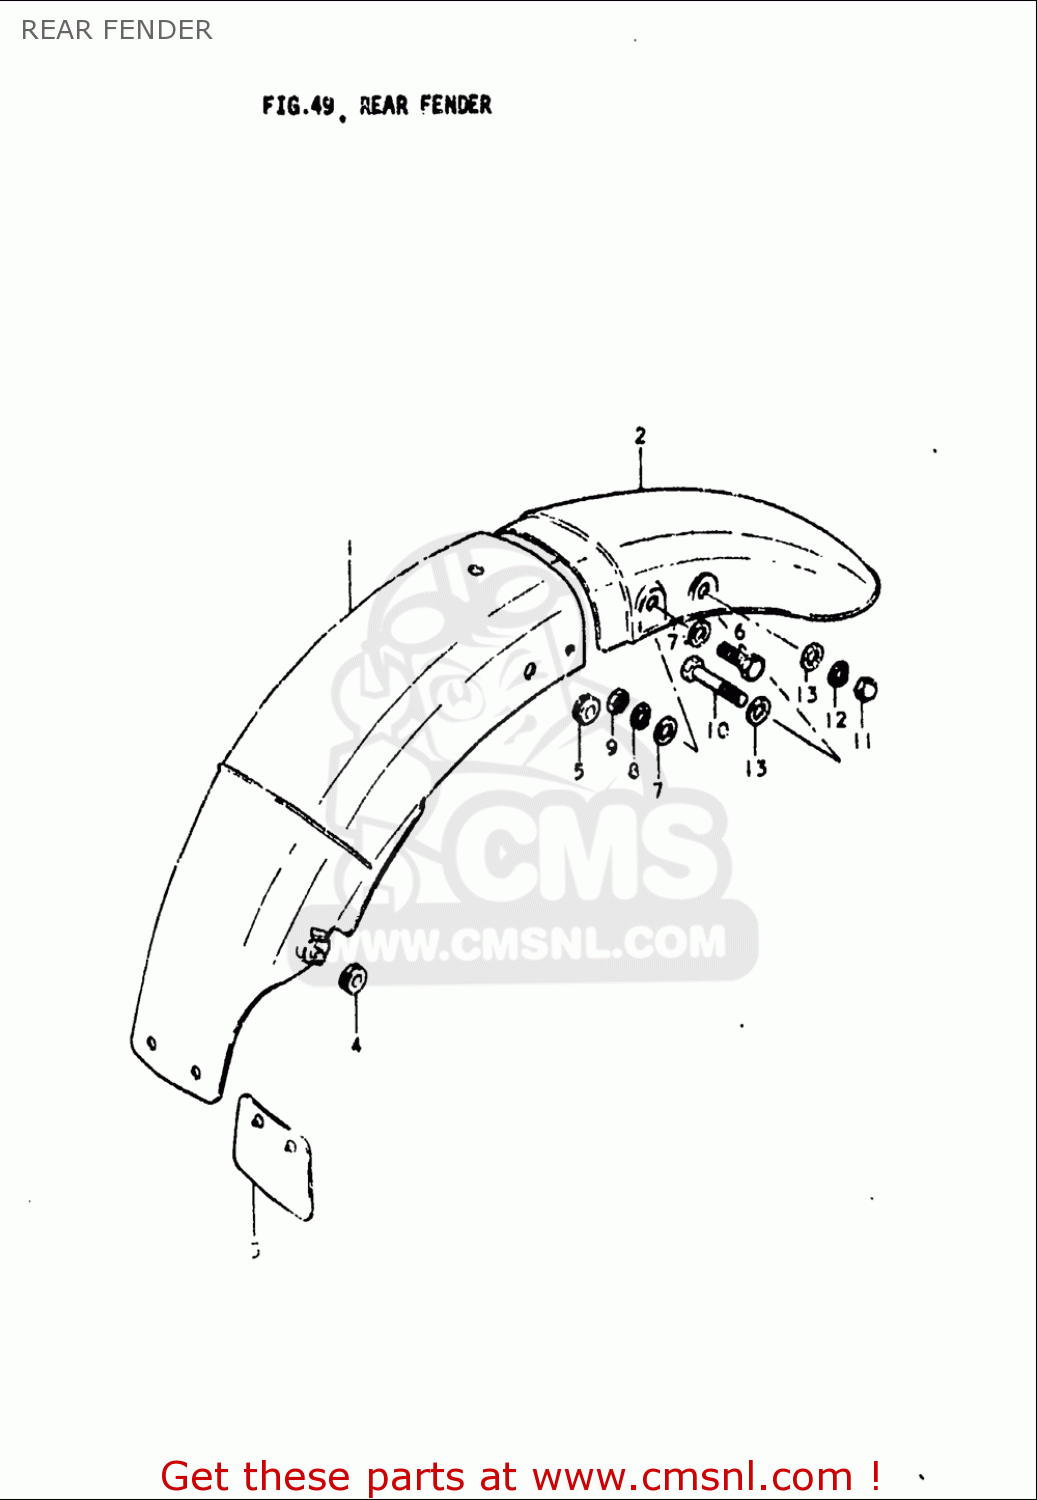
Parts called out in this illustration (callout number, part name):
3	GUIDE,RR FENDER MUD
4	CUSHION
5	CUSHION
6	BOLT
7	WASHER
8	WASHER,LOCK
9	NUT
10	BOLT
11	NUT
12	WASHER,LOCK
13	WASHER
